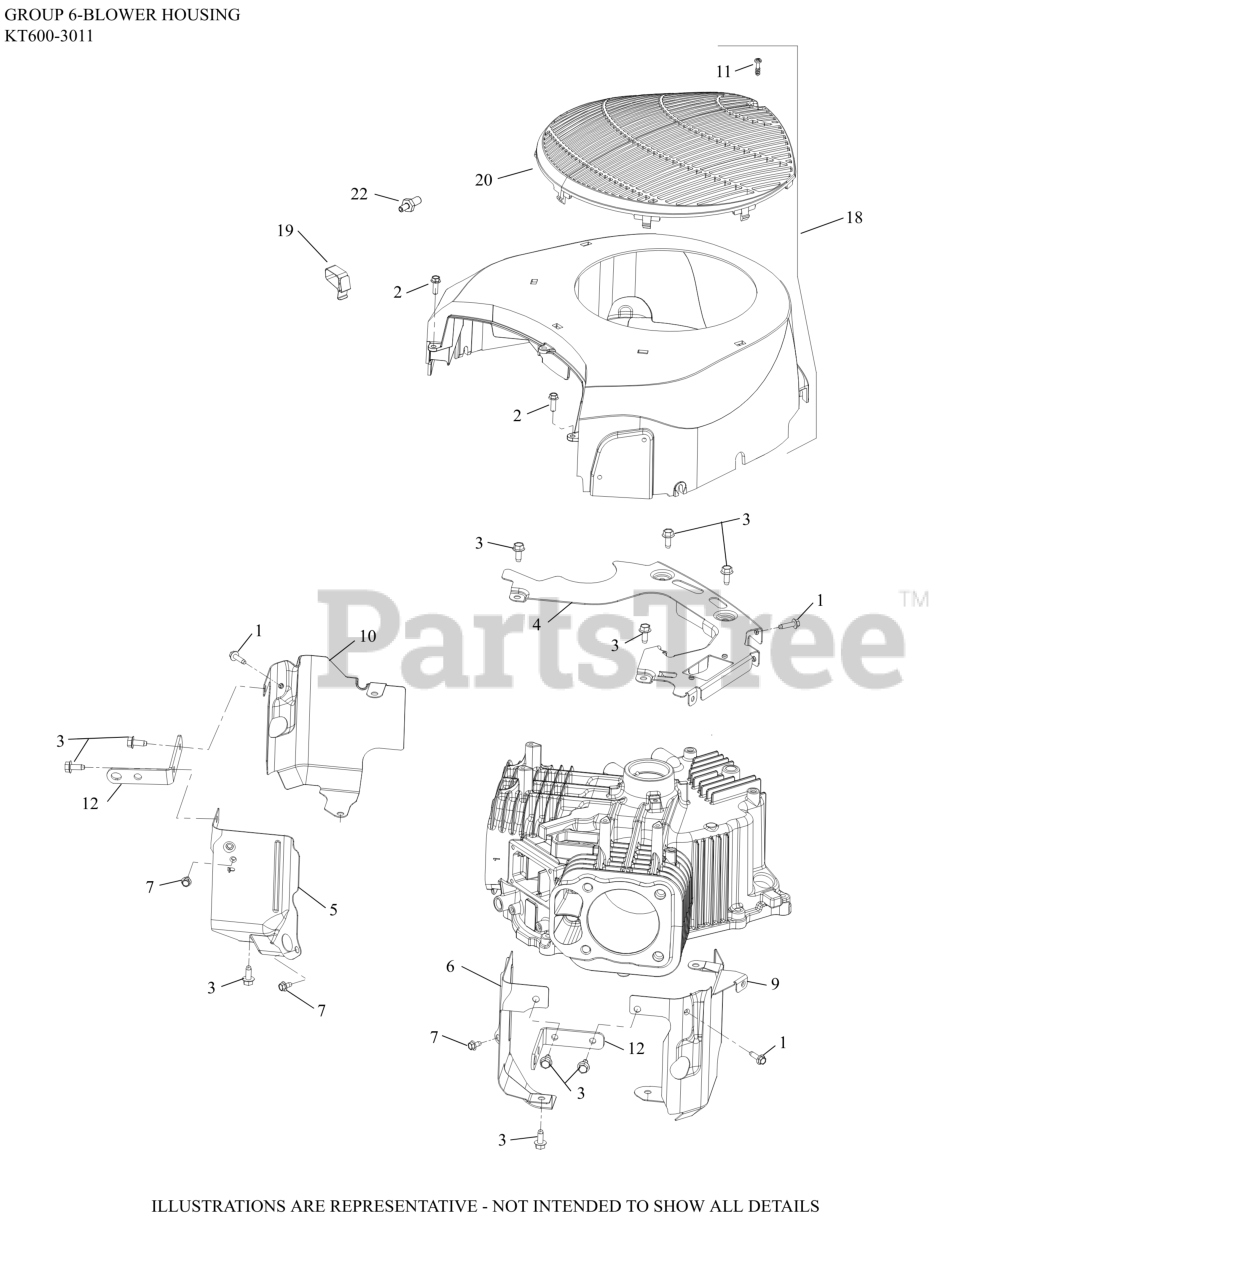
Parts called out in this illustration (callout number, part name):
1	SCREW, THD FRM-USE 25 086 473-S
2	SCREW, HI-LOW
3	SCREW, THREAD FORMING
4	PLATE, BACKING
5	BAFFLE, VALLEY #1
6	BAFFLE, VALLEY #2
7	SCREW, THREAD FORMING
9	BAFFLE, LEFT BARREL
10	BAFFLE, RIGHT BARREL
11	SCREW, M5-2.42 (PT) THREAD
12	STRAP, LIFTING
18	KIT, BLOWER HOUSING
19	CLIP, BLOWER HOUSING
20	GUARD, FIXED
22	BOLT, ENGINE GROUND
